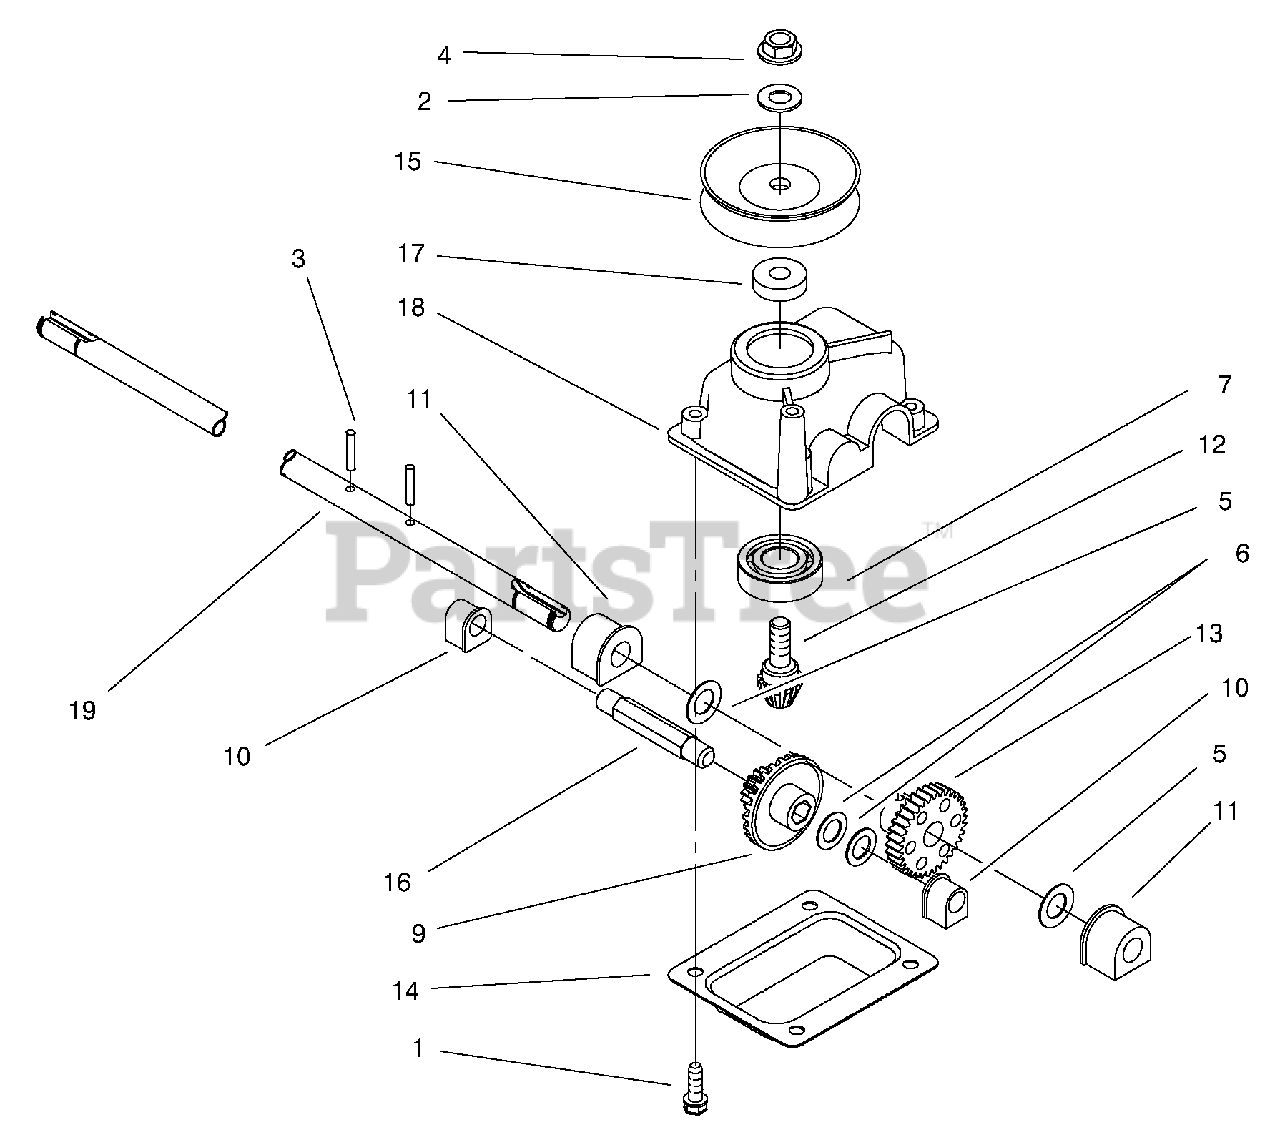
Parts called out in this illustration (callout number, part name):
1	Screw-HH
2	Washer-Flat
3	Pin-Groove
4	Nut-Lock, NI
6	Washer-Thrust
7	Bearing-Ball
9	Gear-15t Spur, 37t Bevel
11	Bushing-Output
12	Gear-Bevel, Pinion
13	Gear-34t
14	Cover-Gear Case
15	Half-Pulley
16	Shaft-Intermediate
18	Gearcase
19	Shaft-Output
